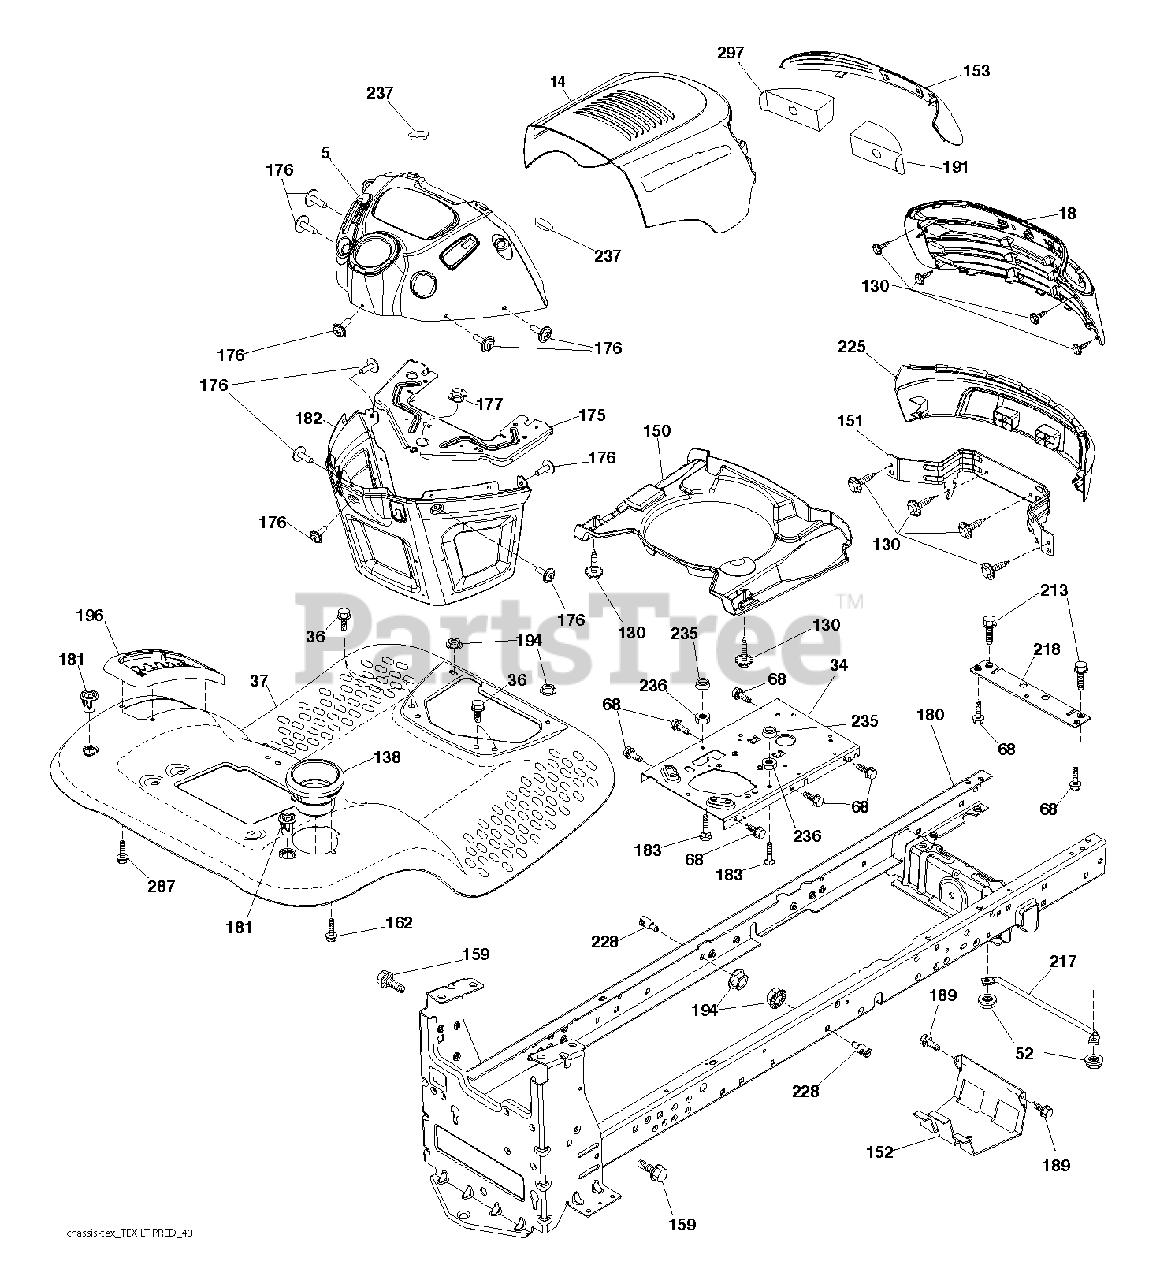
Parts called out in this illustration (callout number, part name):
5	DASH.PRED.LT.ELE.GAUGE.BLACK
14	HOOD.PREDATR.LT.U-FRM.TPVNT428
18	GRILLE.SVC.BASE.PREDATOR.LT428
34	PLATE.ENGINE.WELDED.CHASSIS
36	SCREW 5/16"
52	LOCKNUT
130	SCREW.#10 X 0.750.BOS THREAD
138	CUPHOLDER.TL.TEX.BLACK
150	DUCT.AIR.TOP.VENT.PREDATOR.LT
151	BRACKET.PIVOT.ALPHA.LT
152	SHIELD BROWNING
153	LENS.PREDATOR.LT.
159	SCREW, 3/8-16X3/4
162	SCREW.HI-LO.CONSOLE
176	SCREW.#10-24X5/8.RN.QU
177	BUSHING STEERING
180	CHASSIS
181	FEND/FTRST.PCH.CPH.NFW
182	DASH.LWER.PREDATOR/HUSQ.LT
183	BOLT.5/16-18X1-1/4 FULL THD
189	SCREW
191	INSERT.REFLECT.PREDATOR.LT.RH
194	NUT LOCK HEX FLANGE 5/16-18
213	BOLT
217	ROD.PIVOT.HOOD
218	X-PIECE.HOOD.STOP.NON/
228	STUD.FASTNER.W/ANTI-ROTATE
235	SPACER FENDER
236	NUT.CENTERLOCK.5/16-
237	PLUG.MOUNT.CARGO.BLK
297	REFLECTOR.INSERT.PRED.LH.LT
